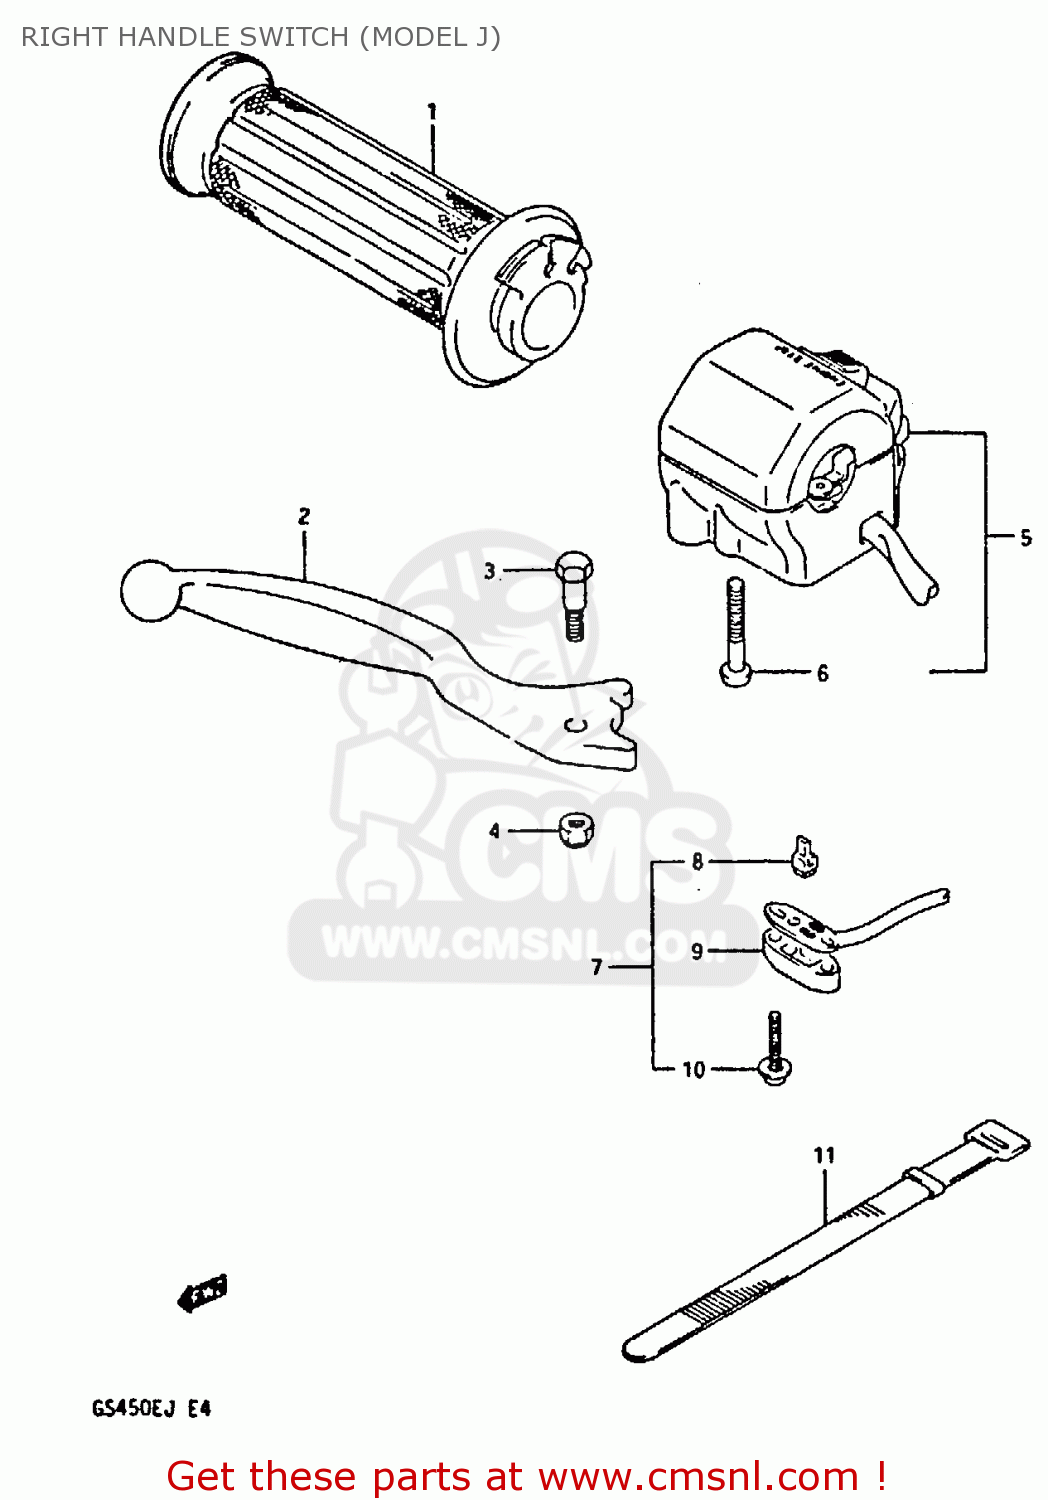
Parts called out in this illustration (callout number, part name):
1	GRIP,THROTTLE
2	LEVER,BRAKE
3	BOLT,LEVER PIVOT
4	NUT
5	SWITCH ASSY, HANDLE RH
6	SCREW, 5X45
7	SWITCH ASSY,STOP
8	CONTACT,SWITCH
9	COVER,FR BK TERMINAL BASE
10	SCREW
11	CLAMP(L:120)
